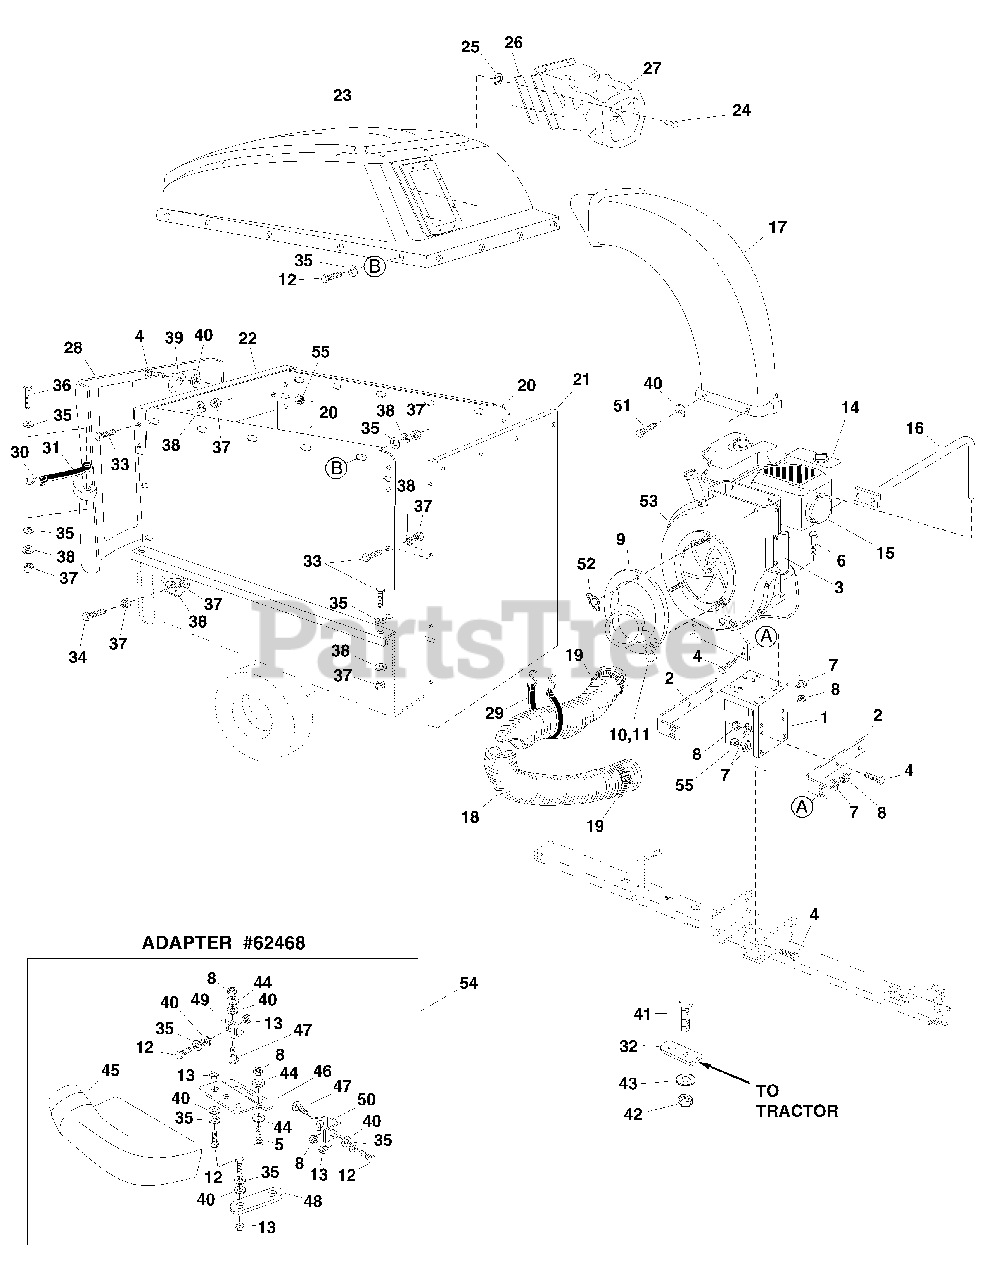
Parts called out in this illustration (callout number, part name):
1	Engine Base
2	Brace, Housing
3	Hose Hanger Bracket Ass'y.
4	Bolt, Hex 5/16-18 x 3/4"
5	Bolt, Hex 5/16-18 x 1"
6	Bolt, Hex 5/16-18 x 1-1/2"
7	Lockwasher, 5/16" Spring Type
8	Nut, Hex Lock 5/16-18
9	Assembly, Hose Adapter (Nozzle) (Includes items 10 and 11))
10	Bracket, Switch (Actuator)
11	Rivet, Pop 5/32"
12	Bolt, Hex 1/4-20 x 3/4"
13	Nut, Hex Lock 1/4-20 Thd.
15	Deflector, Muffler
16	Hose Hanger Rod Ass'y.
18	Hose (6" x 84")
19	Hose Clamp 6"
23	Hard Top Assembly (Includes 24,25,26,27)
24	Rivet, 3/16"
25	Washer, Flat 3/16"
26	Boot Mounting Strap
27	Hard top Boot
28	Poly Rear Door
29	Strap, Tarp 25"
30	S Hook, #32
31	Strap, Tarp (Less Hooks)
32	Hitch Plate
33	Bolt, Hex 1/4-20 x 5/8"
34	Bolt, Hex 1/4-20 x 1"
35	Washer, 1/4" STD
36	Bolt, Hex 1/4-20 x 1-1/4"
37	Nut, Hex 1/4-20
38	Lockwasher, Spring 1/4"
39	Door Latch
40	Washer, Nylon 21/64"
41	Bolt, Hex 1/2-13 x 1-1/4"
42	Nut, Hex Lock 1/2-13
43	Washer, Flat 7/16"
44	Washer, 5/16" STD
45	Adapter, Deck
46	Bracket, Deck Adapter
47	Bolt, Carr. 5/16" x 3/4"
48	Mounting Strap
49	Angle Bracket
50	Mounting Bracket
51	Screw, Self Tap 5/16-18 x 3/4"
53	Impeller Housing Assembly
54	Deck Adapter Kit
55	Nut, Nylock 5/16-18
